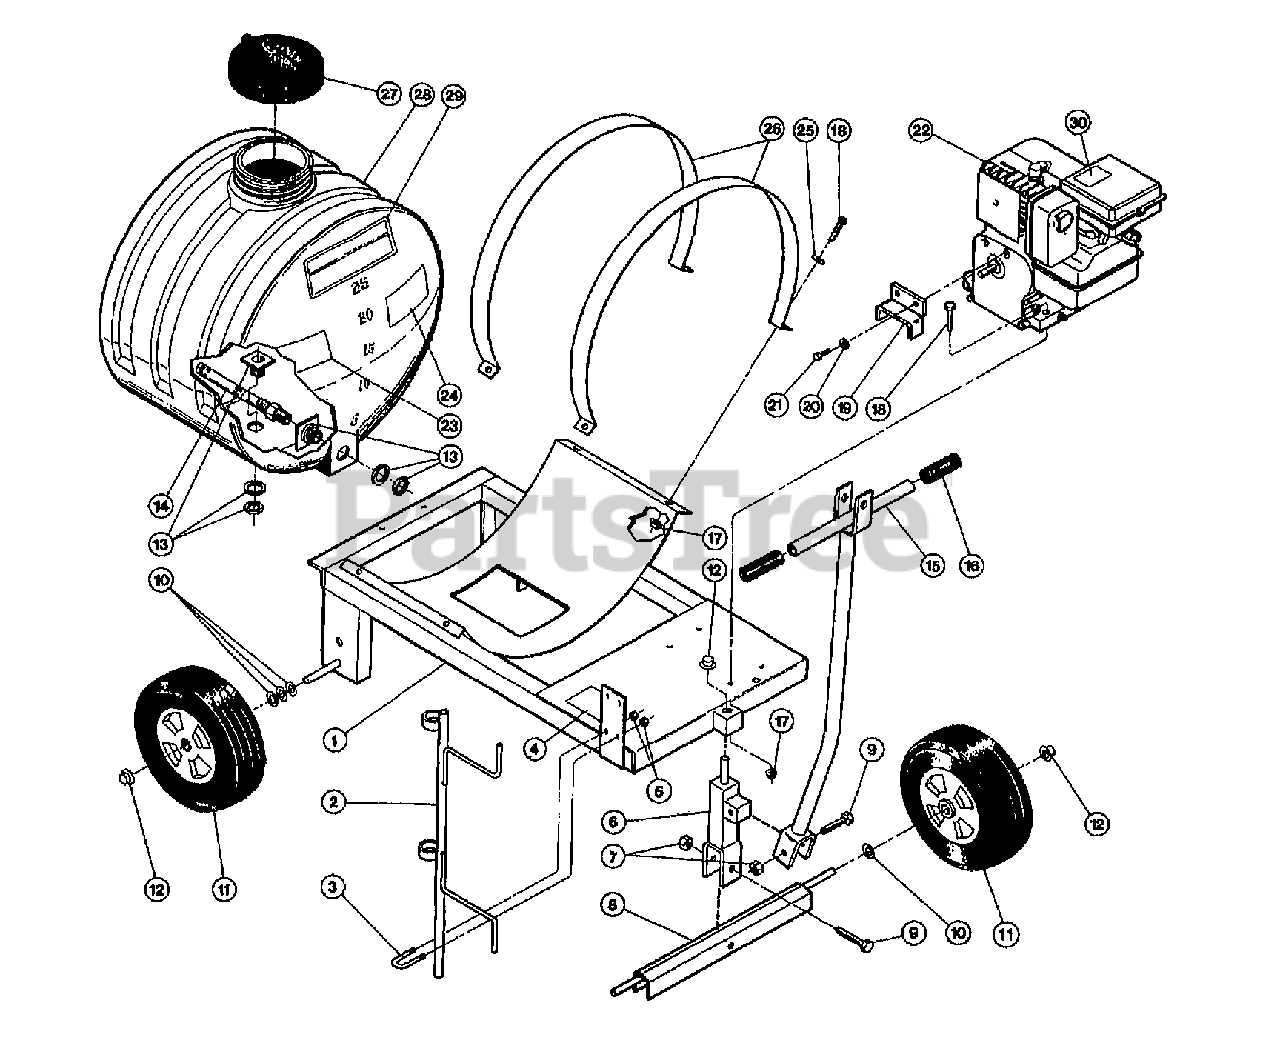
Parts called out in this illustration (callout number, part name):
1	ASSM-UNDERCARRIAGE
2	ASSM-GUN/HOSE STAND
3	BOLT-U 1/4X1X3/4 SPRAYER
4	DECAL-SAVE
5	NUT-HEX 1/4-20 ZP
6	ASSM-AXLE PIVOT FRONT
8	ASSM-FRONT AXLE SPRAYER
9	SCR-HH 5/8-11X2.25 G5 ZP
10	WASHER-1.75X.625X.11
11	ASSM-TIRE/WHEEL 11592
12	NUT-PUSH 5/8
13	ASSM-BULK HEAD W21254002
14	AGITATOR-JET W33710019
15	ASSM-TOW HANDLE W/O GRIPS
16	HANDLEGRIP-25 GAL SPRAYER
17	NUT-HFLK 5/16-18 ZP
18	SCR-HH 5/16-18X1.5 G5 ZP
19	COVER-DRIVESHAFT SPRAYER
20	WASHER-LK .312 ZP
21	SCR-GRD 5 W02050502FP
22	ENGINE, 3HP BRIGGS & STRATTON #80232
23	DECAL-DANGER AVOID W2045146
24	DECAL-ENG SPEED W2045149
25	WASHER-FLAT 5/16 SAE
26	STRAP-TANK SECURING
27	CAP-TANK W21254503
28	ASSM-TANK 25 GAL W/DECALS
29	DECAL-LOGO 25 GAL SPRAYER
30	DECAL-HOT SURFACE
